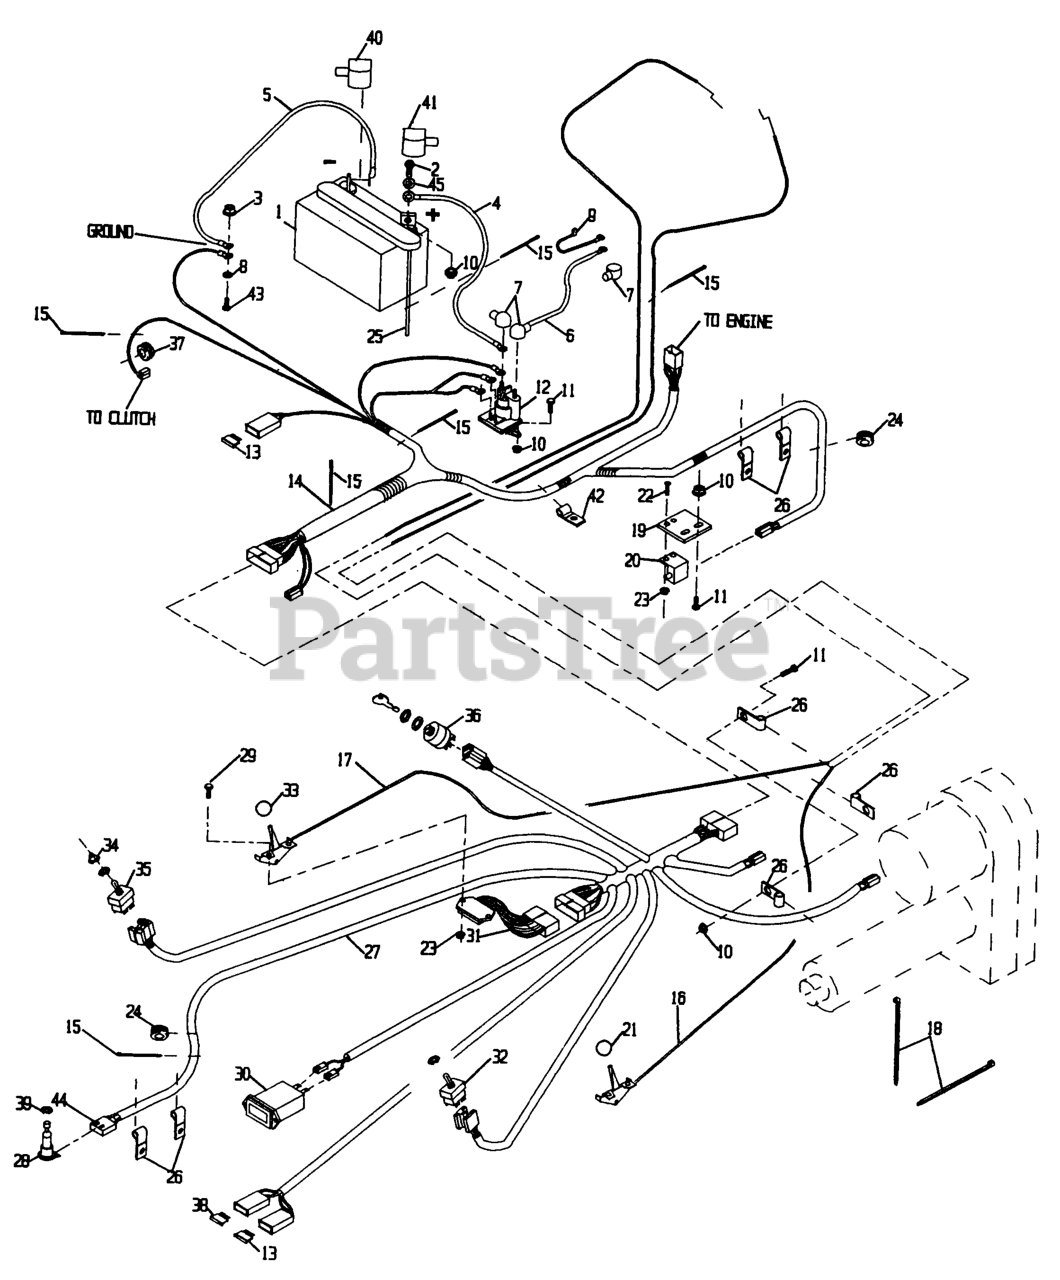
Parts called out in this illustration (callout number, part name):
1	Battery, 12 Volt
5	WIRE-GROUND
6	WIRE,BATTERY POSITIVE
7	INSULATOR-SOLENOID
8	WASHER-SPRING
13	FUSE-BLADE TYPE, 20 AMP
15	TIE-CABLE
16	THROTTLE CABLE ASM
18	TIE-PLASTIC
19	BRACKET,SAFETY SWITCH
20	SWITCH-OPEN, NORMALLY
21	KNOB-BALL
24	GROMMET
26	CLIP-LOOM
28	SWITCH,PUSH BUTTON
30	METER-HOUR
31	MODULE,OPC
32	SWITCH,W/TERM CLIPPD
33	KNOB-BALL, BLACK
34	BOOT-SWITCH, TOGGLE
35	SWITCH-TOGGLE, DPDT
36	SWITCH,IGNITION
37	GROMMET
38	FUSE-BLADE TYPE, 30 AMP
41	INSULATOR, BATTERY -
42	CLIP-LOOM
44	CONNECTOR,PACKARD 2 WAY
